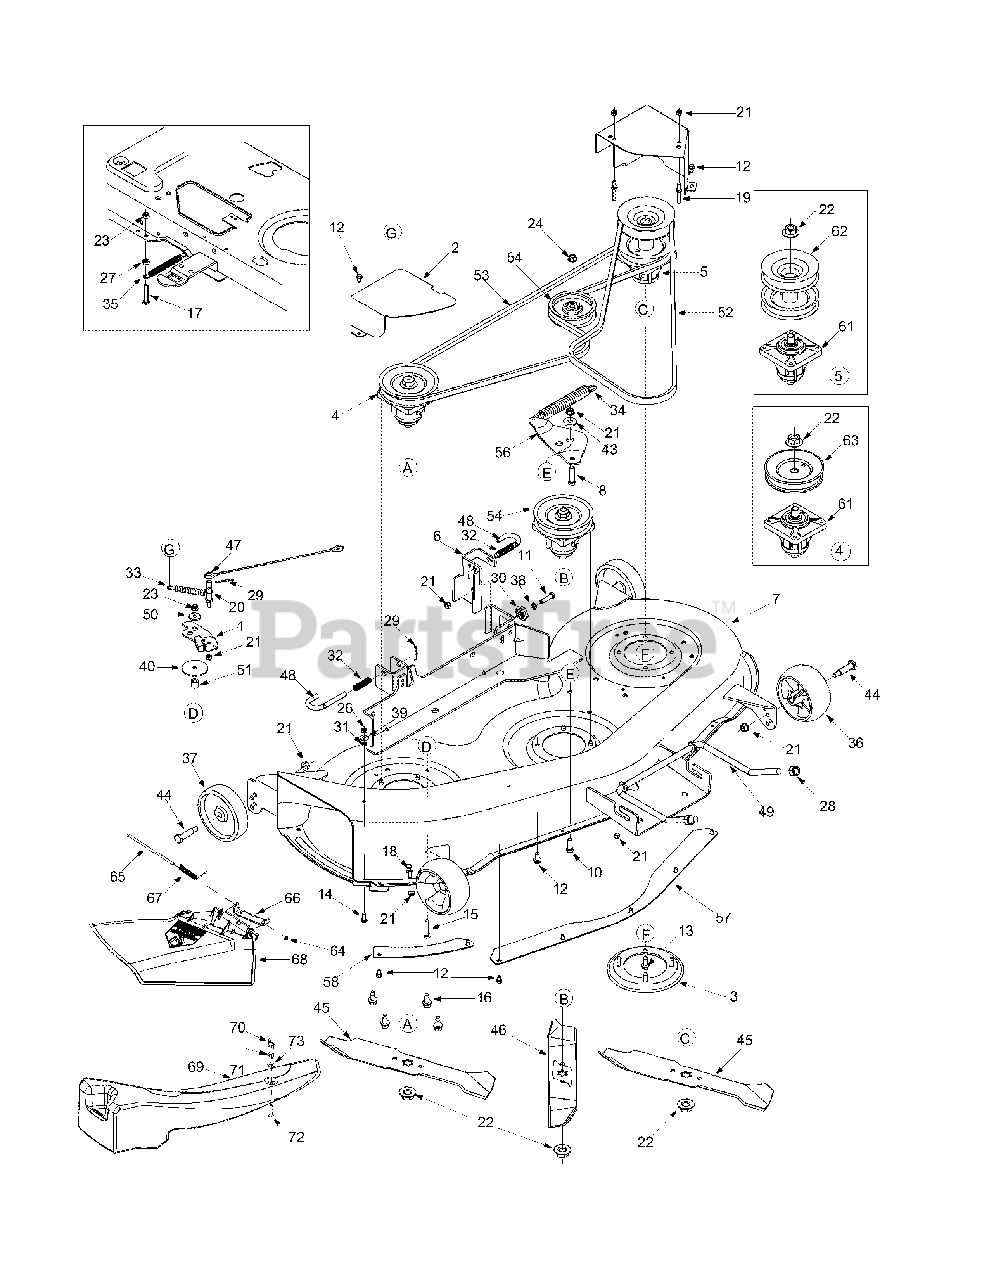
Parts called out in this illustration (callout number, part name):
1	Deck Brake Assembly
3	Spindle Plate
4	Spindle Assembly: Pulley w/ftg.
5	Spindle Assembly: Double Pulley
9	Hex Bolt 1/4-20 x 2.0
10	Hex Bolt 3/8-16 x 1.0
11	Hex Bolt 5/16-18 x 1.25
12	TT Screw 1/4-20 x 0.5
13	TT Screw 5/16-18 x 0.875
14	Hex Bolt 1/4-20 x 0.620
15	Hex Bolt 5/16-18 x 1.5
16	LD Screw 5/16-18 x 0.75
17	Hex Bolt 5/16-18 x 1.75
18	Grass Catcher Pin
19	Belt Guard Pin
20	Pin 1/4-20
21	Hex Lock Nut 1/4-20
22	Flange Nut
23	Lock Nut 5/16-18
24	Flanged Lock Nut 3/8-16
25	Hex Nut M16
26	Hex Nut 1/4-20
27	Hex Nut 5/16-18
28	Lock Nut 1/2-13
29	Cotter Pin
30	Gear: Deck Adjustment
31	Push Nut
32	Compression Spring
33	Extension Spring
34	Extension Spring
35	Extension Spring
36	Deck Wheel 5.0 dia. Ball
37	Deck Wheel 5.0 x 1.38
38	Lock Washer
39	Bell Washer
40	Flat Washer
41	Lock Washer
43	Shoulder Spacer
44	Shoulder Screw 3/8-16
45	Blade: 16.28" Three in One
46	Blade: 14.88" Three in One
47	Cable: Bracket
48	Rod: Deck Release Handle
49	Rod: Front Adjustment
50	Shoulder Spacer
51	Spacer
52	Belt: V Type
53	Belt: V Type
54	Idler Pulley
56	Idler Bracket
58	Deck Skirt RH
61	Spindle Housing
61	Bearing
61	Spindle Shaft 6.58
61	Spindle Shaft 4.45
61	Ball Bearing
62	Deck Pulley: Double
63	Deck Pulley
64	Speed Nut
65	Hinge Pin
66	Mounting Bracket
67	Torsion Spring
68	Chute Deflector: Side Discharge
69	Mulch Plug (if equipped)
70	Wing Nut (if equipped)
71	Hex Nut (if equipped)
72	Machine Screw (if equipped)
73	Flat Washer (if equipped)
